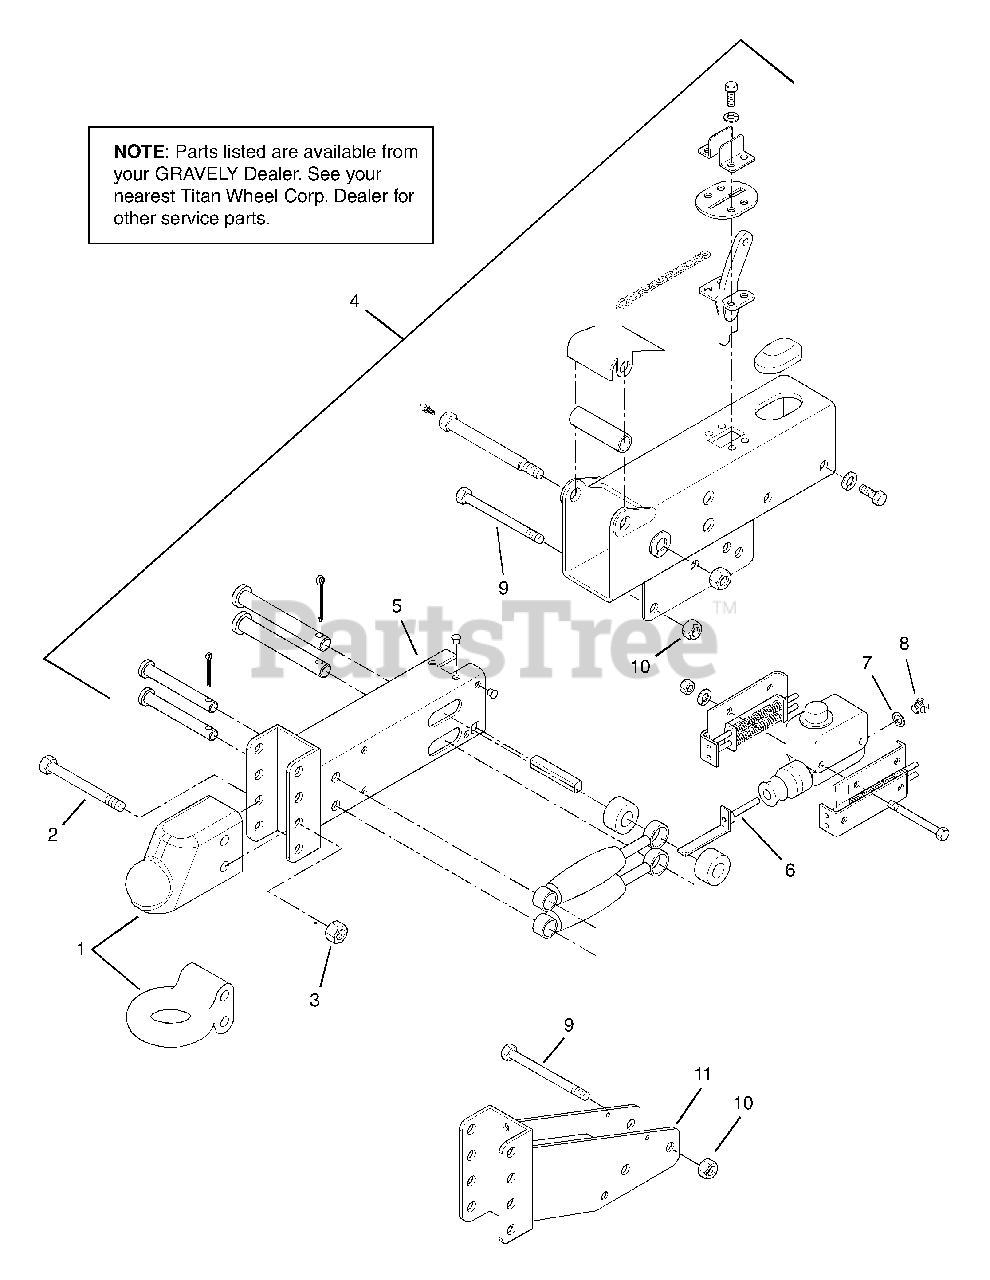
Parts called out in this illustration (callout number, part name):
1	Adjustable Ball Coupler
1	Hitch Ring
2	Bolt-Hex .62-11 x 4.25 Grade 5
3	Nut-Locking-Center .62-11
4	Actuator-Hydraulic Surge
4	1-1/4 Master Cylinder Repair Kit
5	Inner Slide Assembly with Channel
6	Push Rod Assembly
8	Connector
9	Bolt-Hex .50-13 x 4.00 Grade 5
10	Nut-Locking .50-13
11	Hitch Assembly
